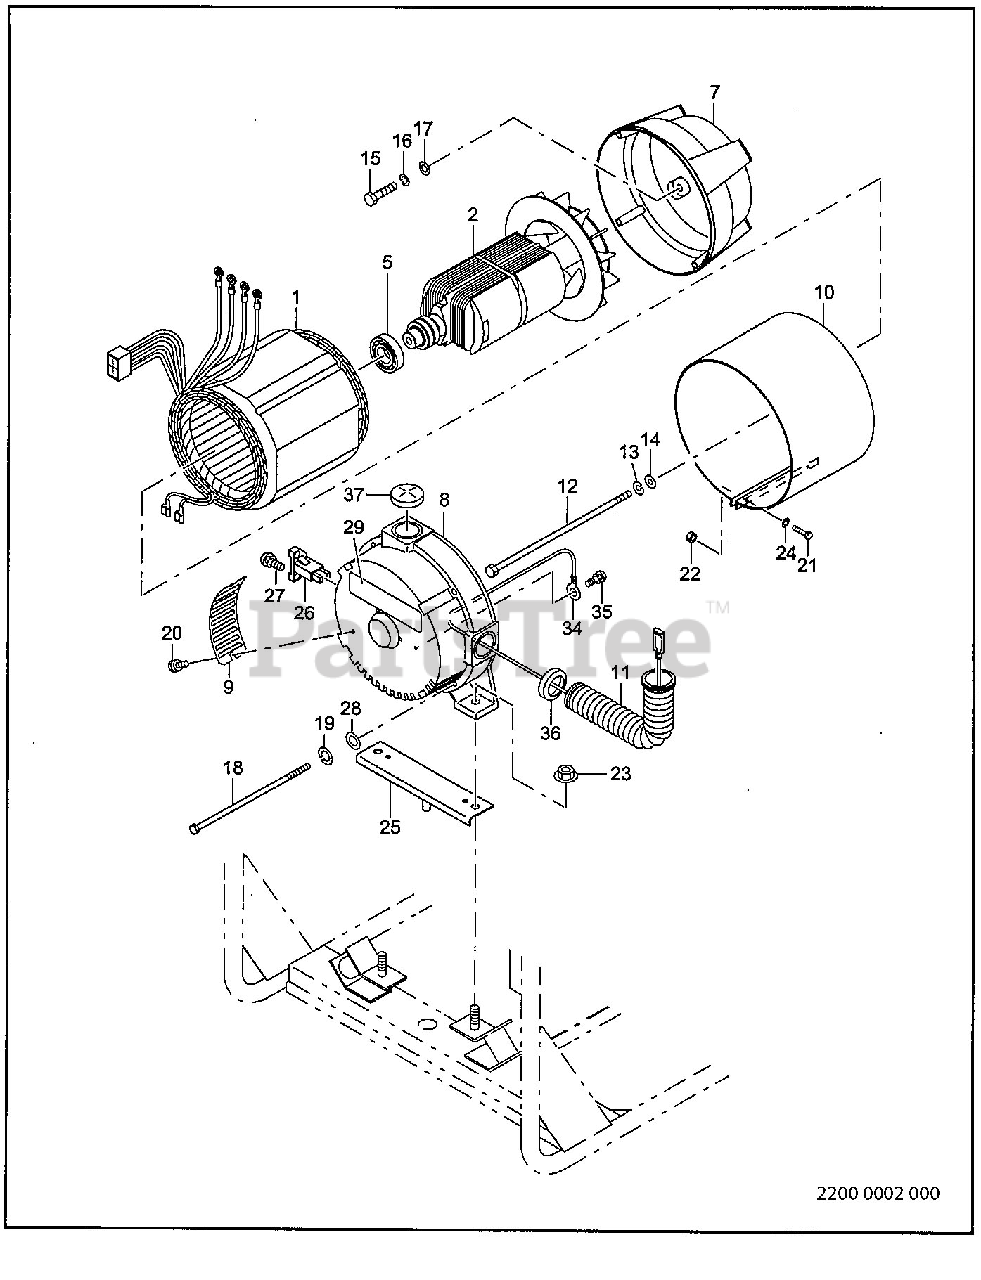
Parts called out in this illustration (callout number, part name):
1	STATOR ASSY
2	ROTOR ASSY
12	THROUGH BOLT
15	BOLT
18	COVER BOLT
20	BOLT and WASHER ASSY
21	BOLT
23	FLANGE NUT
25	GENERATOR BASE
26	BRUSH HOLDER ASSY
27	SCREW and WASHER ASSY
29	LABEL(SPEC)
35	SCREW and WASHER
